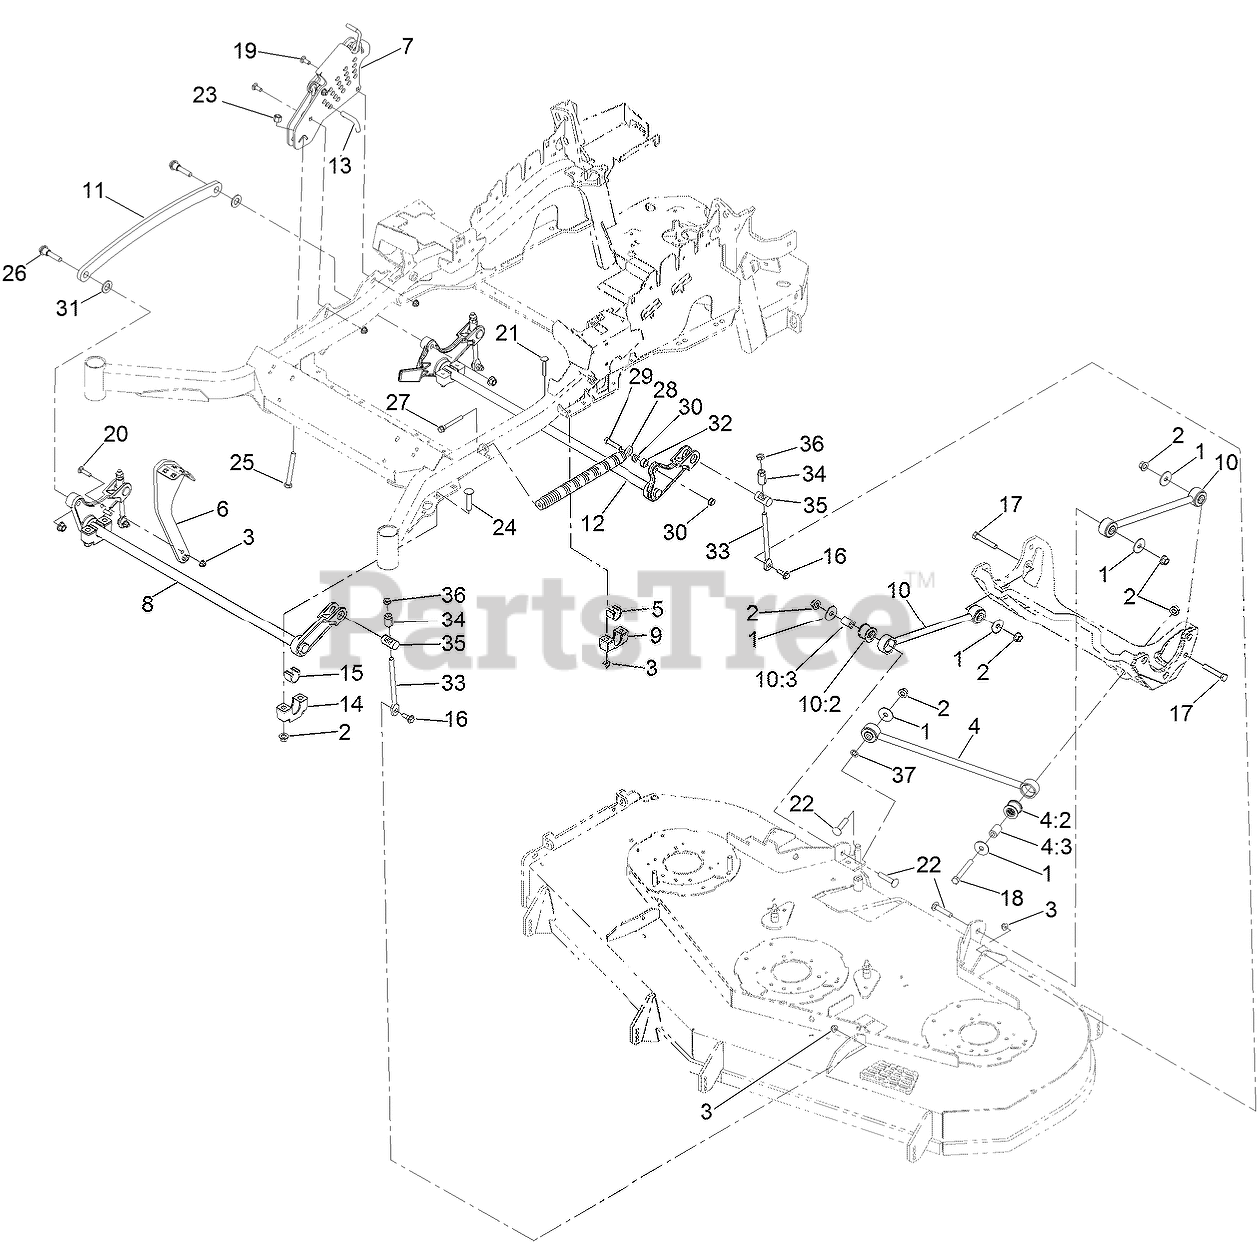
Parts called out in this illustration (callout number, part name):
1	WASHER-THRUST
2	Nut-Lock 1/2-13
3	NUT-HF, NI
4	PANHARD ROD ASM
4:2	BUSHING-SUSPENSION, RUBBER
5	BEARING-CROSS SHAFT, REAR
6	LEVER-FOOT
7	HOC ASM
8	DECKLIFT-FRONT
9	SUPPORT-CROSS SHAFT, BEARING REAR
10	DECK STRUT ASM
10:2	BUSHING-SUSPENSION, RUBBER
11	LINK-LIFT, DECK
12	LIFT-DECK, REAR
13	PIN-HOC
14	SUPPORT-CROSS SHAFT, BEARING
15	BEARING-CROSS SHAFT, FRON
16	SCREW-SHOULDER, HHF
17	SCREW-HH
18	SCREW-HH
19	BOLT-CARR
20	SCREW-CARR
21	Bolt-Carriage 3/8-16 X 2 1/4
22	SCREW-CARR
23	NUT-LOCK, NI
24	Bolt-Carriage 1/2-13 X 2 1/2 Spl Neck
25	BOLT-TAP
26	SCREW-HHF, SHOULDER
27	BOLT-SHOULDER
28	SPRING-EXTENSION
29	SCREW-HH
31	WASHER-FLAT
33	LINK-ADJUSTER, DECK LIFT
34	ADJUSTER-LIFT, DECK
35	TRUNNION
36	NUT-JAM
37	NUT-PUSH
